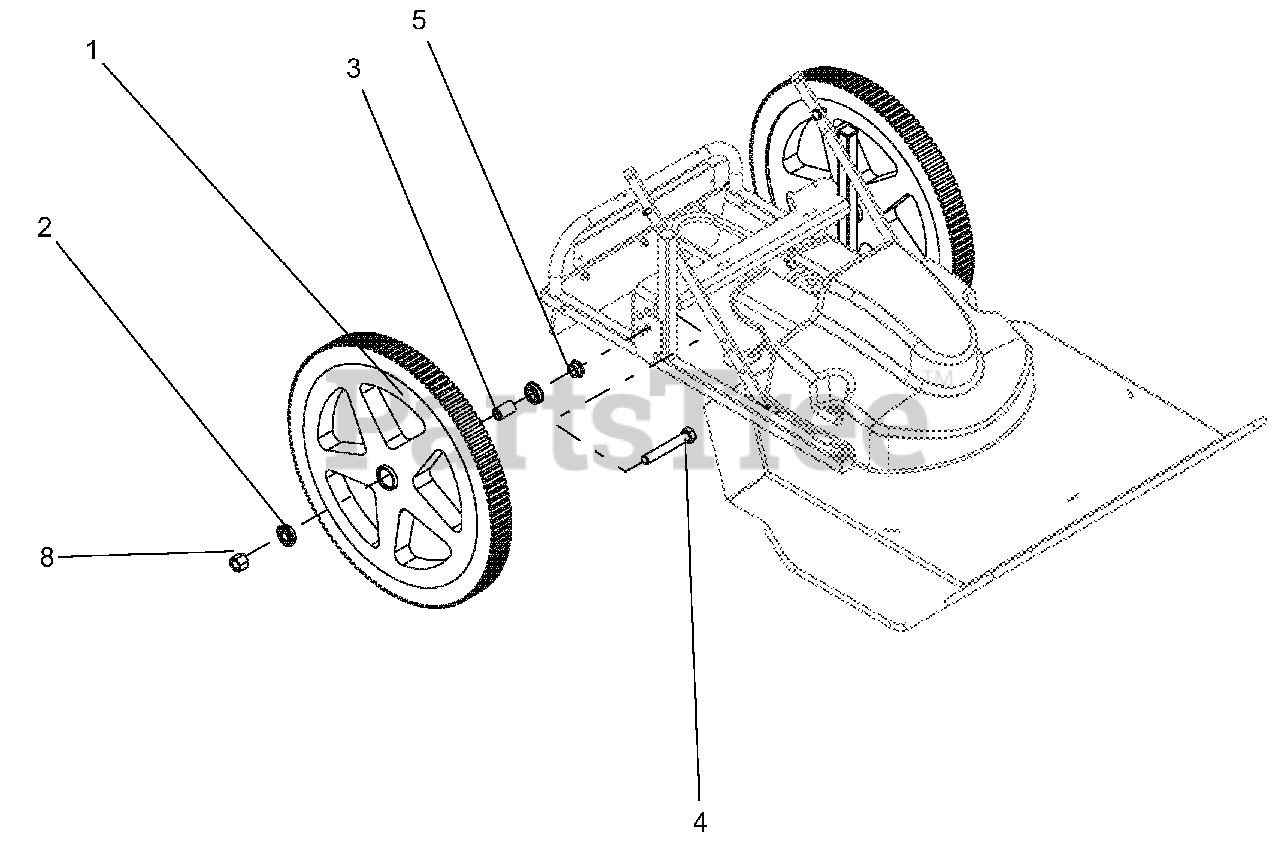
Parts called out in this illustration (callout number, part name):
1	WHEEL/TIRE ASSY, 20"SOLID RBBR
2	BALL BEARING 5/8 ID X 1-3/8OD
3	SPACER, .640X.840X1.39
4	BLT-HEX .62-11X4.00 GR5 FTH YZ
5	NUT-HEX FLANGE .62-11 GR5 YWZC
8	@NUT-LK-NYL .625-11 YWZC
